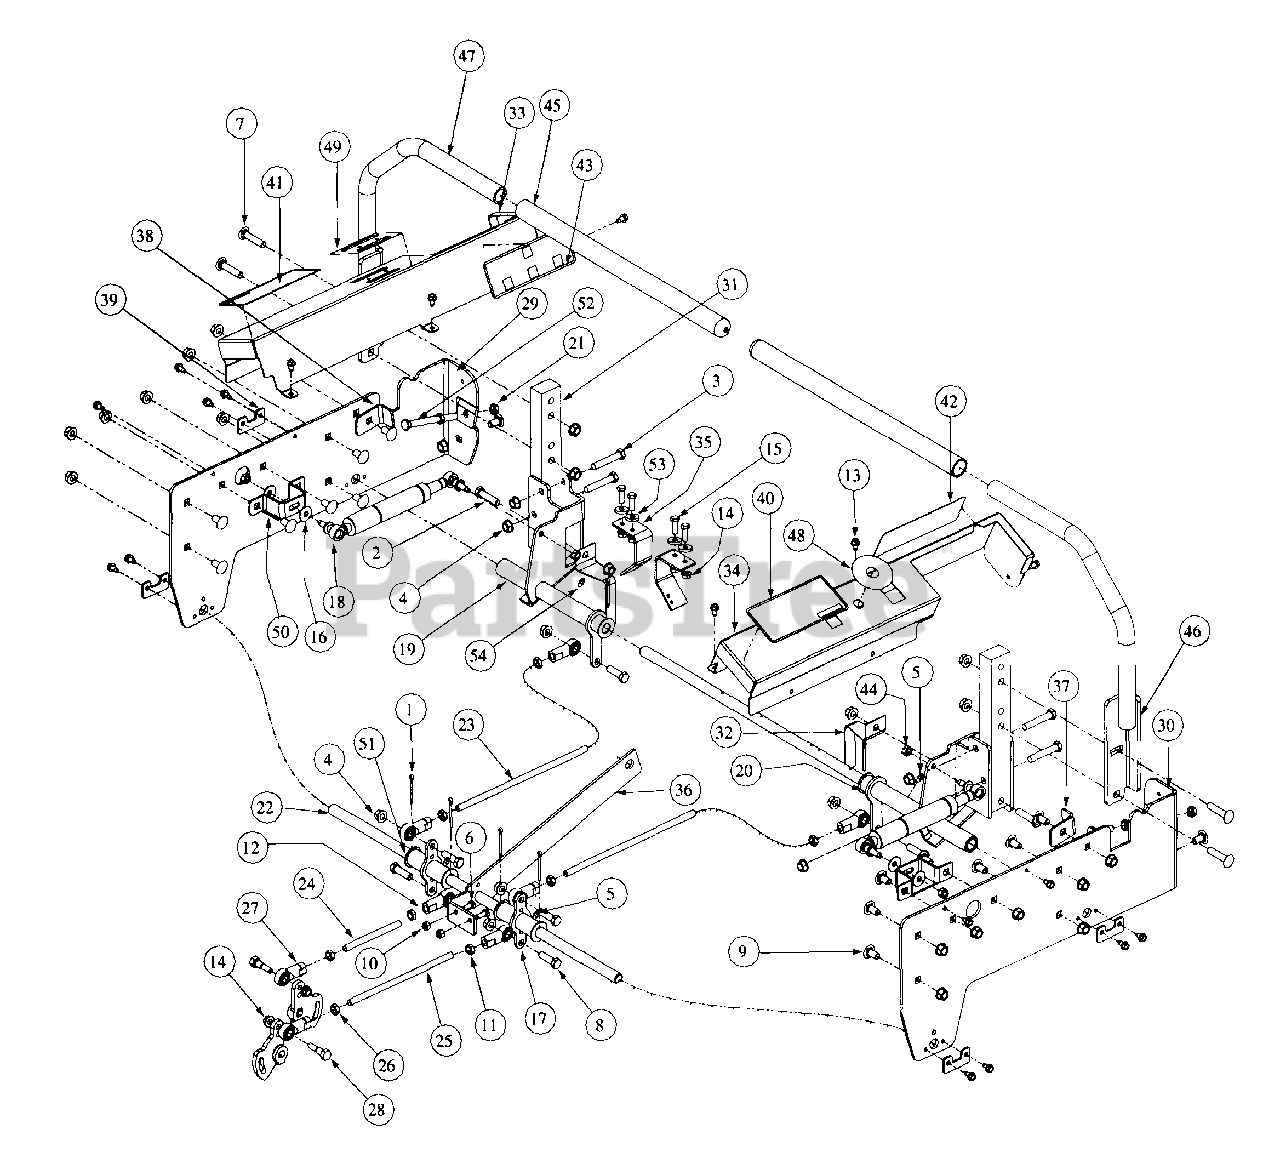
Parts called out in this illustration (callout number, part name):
1	Cotter Pin 5/32 x 1-1/2
2	HHCS, 3/8-16, 2.00
3	HHCS, 3/8-16, 2.25
4	Hex Nut, 3/8-16, Lock Flange
5	Grease Fitting, 1/4-28 x 3/16
6	HHCS, 1/4-20, .620
7	Hex Carriage Screw, 3/8-16, 1.75
8	HHCS, 3/8-16, 1.25
9	Carriage Bolt, 3/8-16 x .75
10	Lock Hex Nut, 1/4-20
11	Hex Jam Nut, 3/8-24
12	B/Joint, 3/8-24, Right Hand Female
13	Screw, TT, 1/4-20, 0.5, Hex I
14	Nut, Lock, Hex Flange, 5/16-18
15	Hex, Cap Screw, 5/16-18 x 3/4
16	Belle Washer, .325 x .930 x .045
17	Belle Crank Assembly
18	Cylinder Return to Neutral
19	Hub Assy, Control LH Bearing
20	Hub Assy, Control RH Bearing
21	Nut, 3/8-16, Jam
22	Shaft Mounting Belle Crank
23	Rod Connector 3/8 OD x 10.125
24	Rod Connector, 3/8 OD x 4.28 LG LH
25	Rod Connector, 3/8 OD x 8.06 LG RH
26	Nut, 3/8-24, Jam, LH Third
27	B/Joint, 3/8-24, LH Female
28	Screw, Shoulder Control Rod
29	Mounting Shaft, Control, Left
30	Mounting Shaft, Control, Right
31	Mounting Handle
32	Lever, Safety Switch
33	Control Panel, LH
34	Control Panel, RH
35	Switch Mounting Bracket, Lapbar
36	Link Mounting Control Shaft, Bracket
37	Stop, RH
38	Stop, LH
39	Holder Shaft, Park Brake
40	Decal, Right Hand Console
41	Decal, Left Hand Console
42	Decal Right Hand Control
43	Decal, Left Hand Control
44	Nut, Hex, Center Lock, M8
45	Grip, 1.0
46	Lapbar, Weldment, Right Handle
47	Lapbar, Weldment, Left Handle
48	Label, Ignition, 2.5 Diameter
49	Label, Control, Throttle and Choke
50	Bracket Assembly, Mount Dampener
51	Flat Washer, 5/8 Nylon
52	HHCS, 3/8-16, 3.00
53	Flat Washer, 5/16
54	Fitting Grease 90°.
